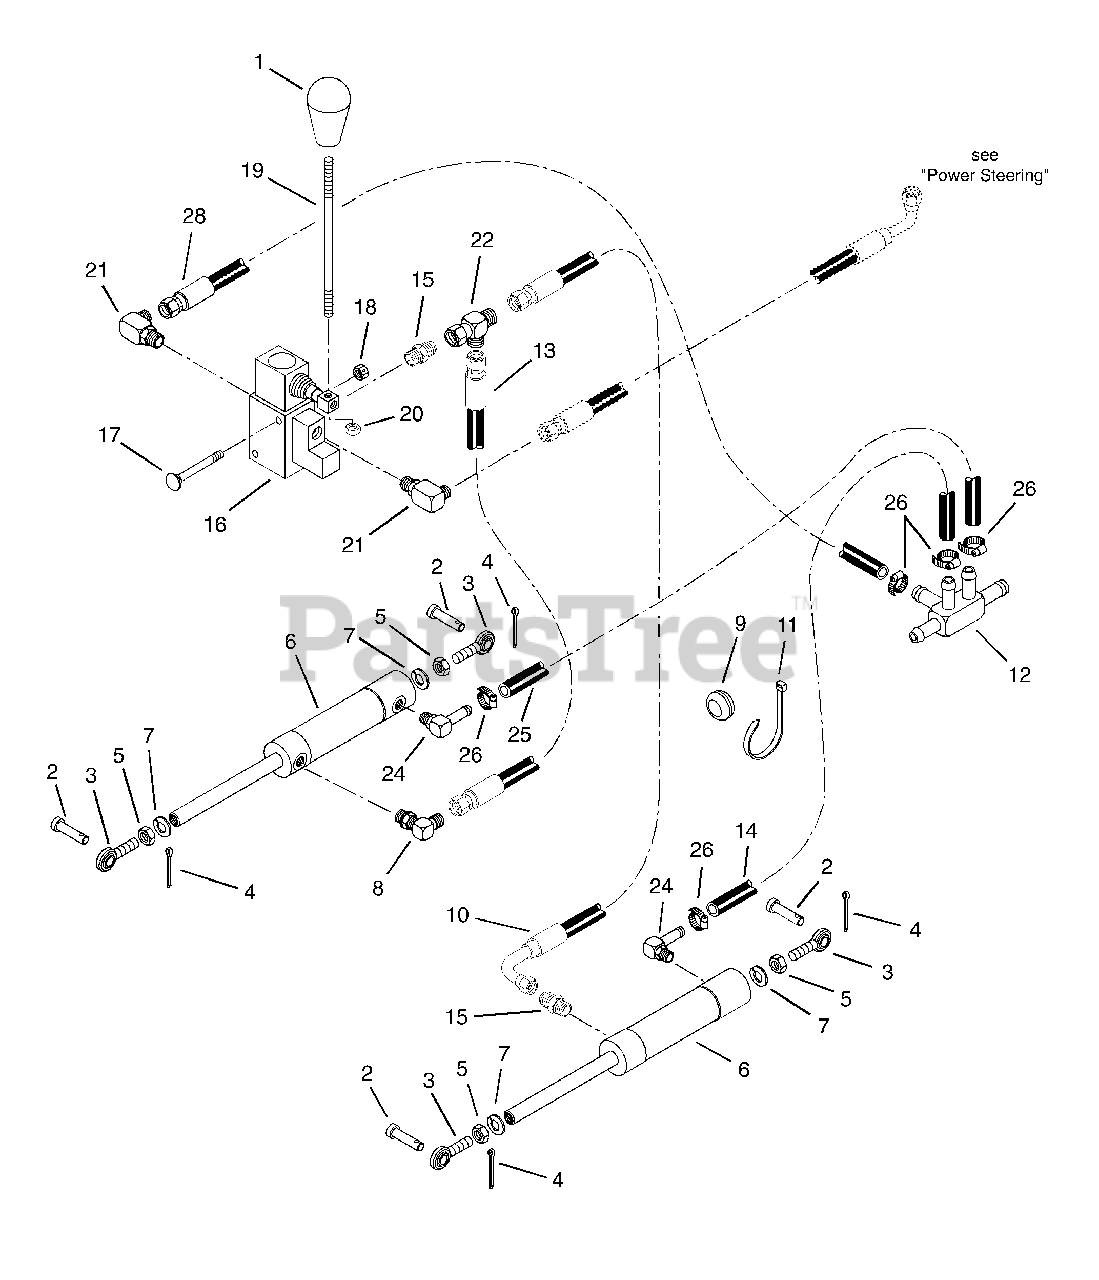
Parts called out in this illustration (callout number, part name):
1	Knob
2	Pin-Clevis .50 x 1.33
3	Rod End. .50-20 Right Hand
4	Pin-Cotter .12 x 1.25
5	Nut-Jam .50-20
6	Cylinder, Lift
7	Washer-Lock .50 Regular
8	Adapter
9	Grommet, 1.25
10	Assembly, Hydraulic Hose
11	Tie Wrap, Black
12	Fitting-Manifold .38 x 1.50
13	Assembly, Hydraulic Hose
14	Hose, 3/8 inch x 24 inch
15	Adapter-Pipe
17	Bolt-Round Head Square Neck .31-18 x 2.25
18	Nut-Locking-Center .31-18
19	Control Rod
20	Nut-Jam M10-1.5
21	Fitting, Adapter
22	Adapter, Fitting Tee
23	Fitting, Adapter .562-18
24	Hose, 3/8 inch x 27 inch
25	Hose Clamp
26	Hose, Hydraulic
